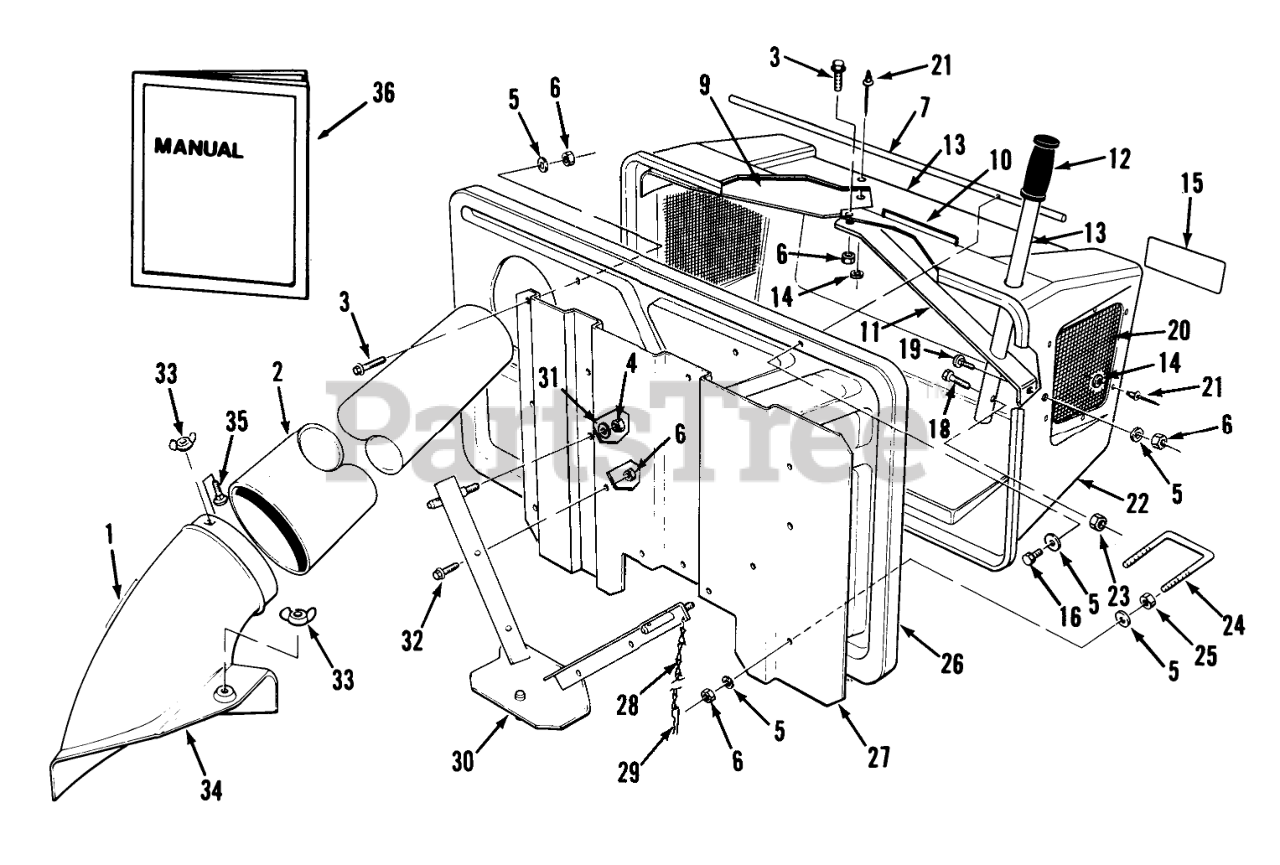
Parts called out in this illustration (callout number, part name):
1	DECAL-DANGER
3	SCREW-HHF
4	NUT-LOCK, NI
5	WASHER-FLAT
6	NUT-LOCK, NI
7	PIVOT ROD
9	DEFLECTOR
10	DECAL
11	HANDLE GUIDE
13	HANDLE TUBE
14	WASHER-FLAT
15	EASY EMPTY BAG DECAL
16	SCREW-HH
18	SCREW-HH
19	BOLT-CARR
20	SCREEN
21	RIVET-POP
22	HOPPER
23	NUT-HEX, SIDE DEFORM
24	LATCH
25	NUT-HEX
27	Plate-Mounting
28	6-LINK CHAIN W/HOOK
29	PIN-HAIR
30	V-Bracket
31	WASHER-FLAT
32	SCREW-HH
33	NUT-WING SPECL
34	Chute
35	BOLT-CARR
36	59047 EASY-EMPTY GR
